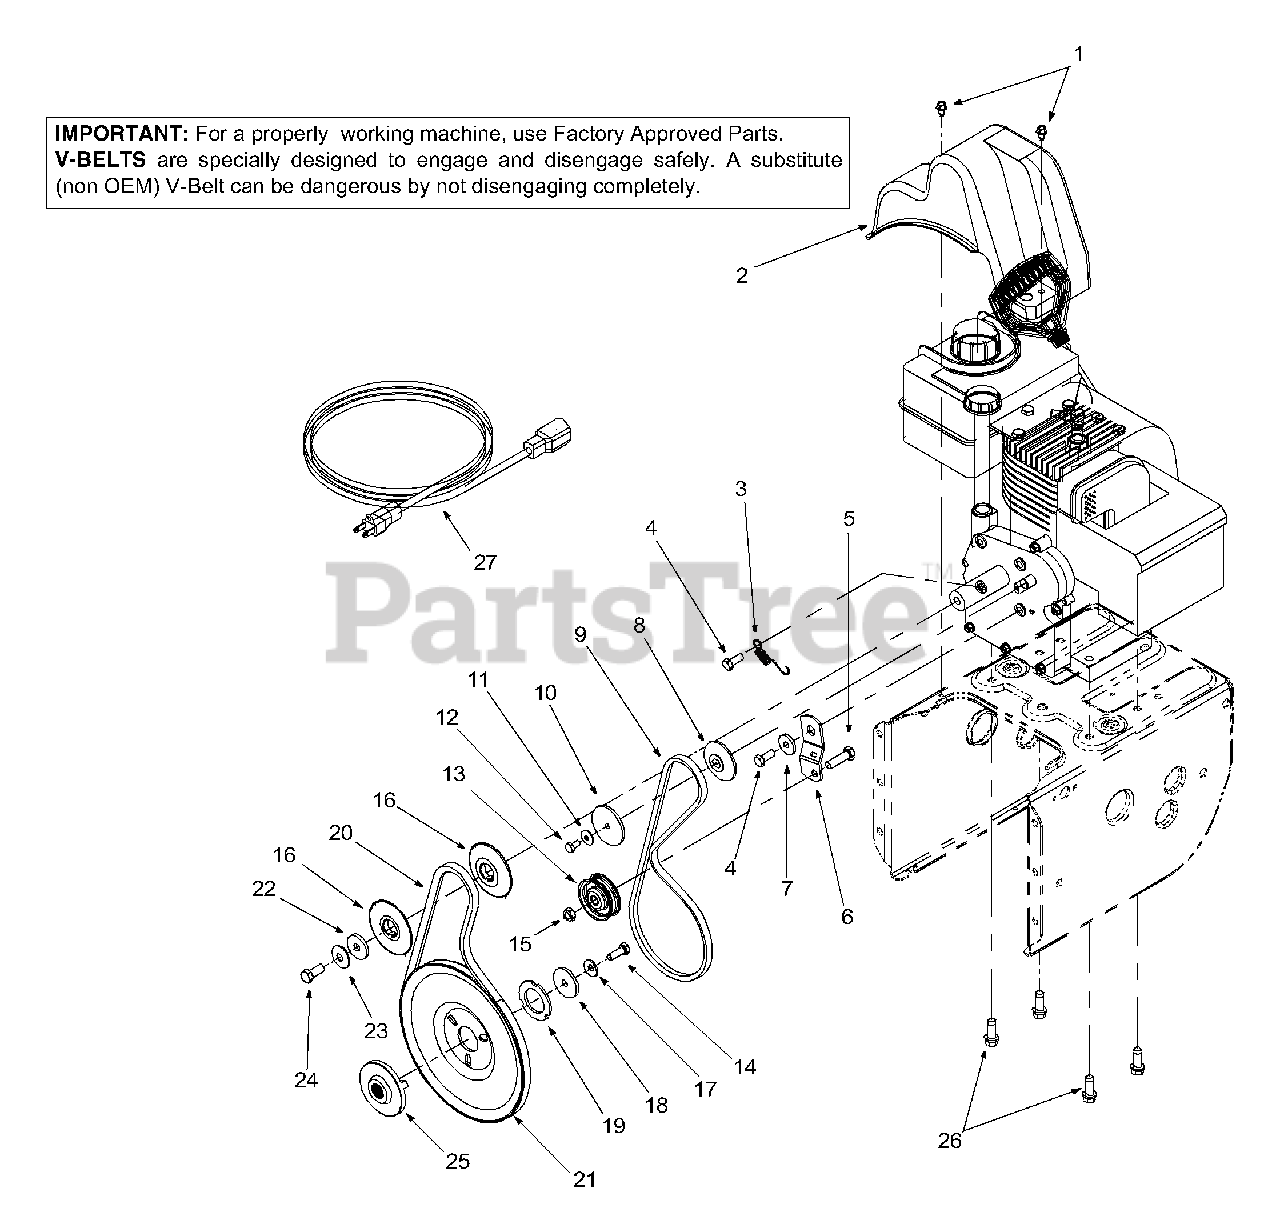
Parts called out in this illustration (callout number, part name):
1	Hex Washer Screw 1/4-20 x.5
2	Belt Cover
3	Extension Spring
4	Hex Screw 5/16-24 x .75
5	Hex Cap Screw 3/8-16 x 1.25
8	Pulley Half
9	V-Belt
10	Pulley Half
11	Bell Washer
12	Hex Cap Screw 1/4-28 x .50
13	Flat Idler
14	Lock Cap Screw 5/16-24
15	Lock Jam Nut 3/8-16
16	Pulley Half
17	Bell Washer
18	Flat Washer
19	Special Washer
20	Belt
21	Auger Pulley
22	Flat Washer
23	Bell Washer
24	Hex Cap Screw 3/8-24
25	Pulley Adapter
26	Hex Washer Screw 3/8-16 x 1.0
27	Extension Cord, Three-Prong
